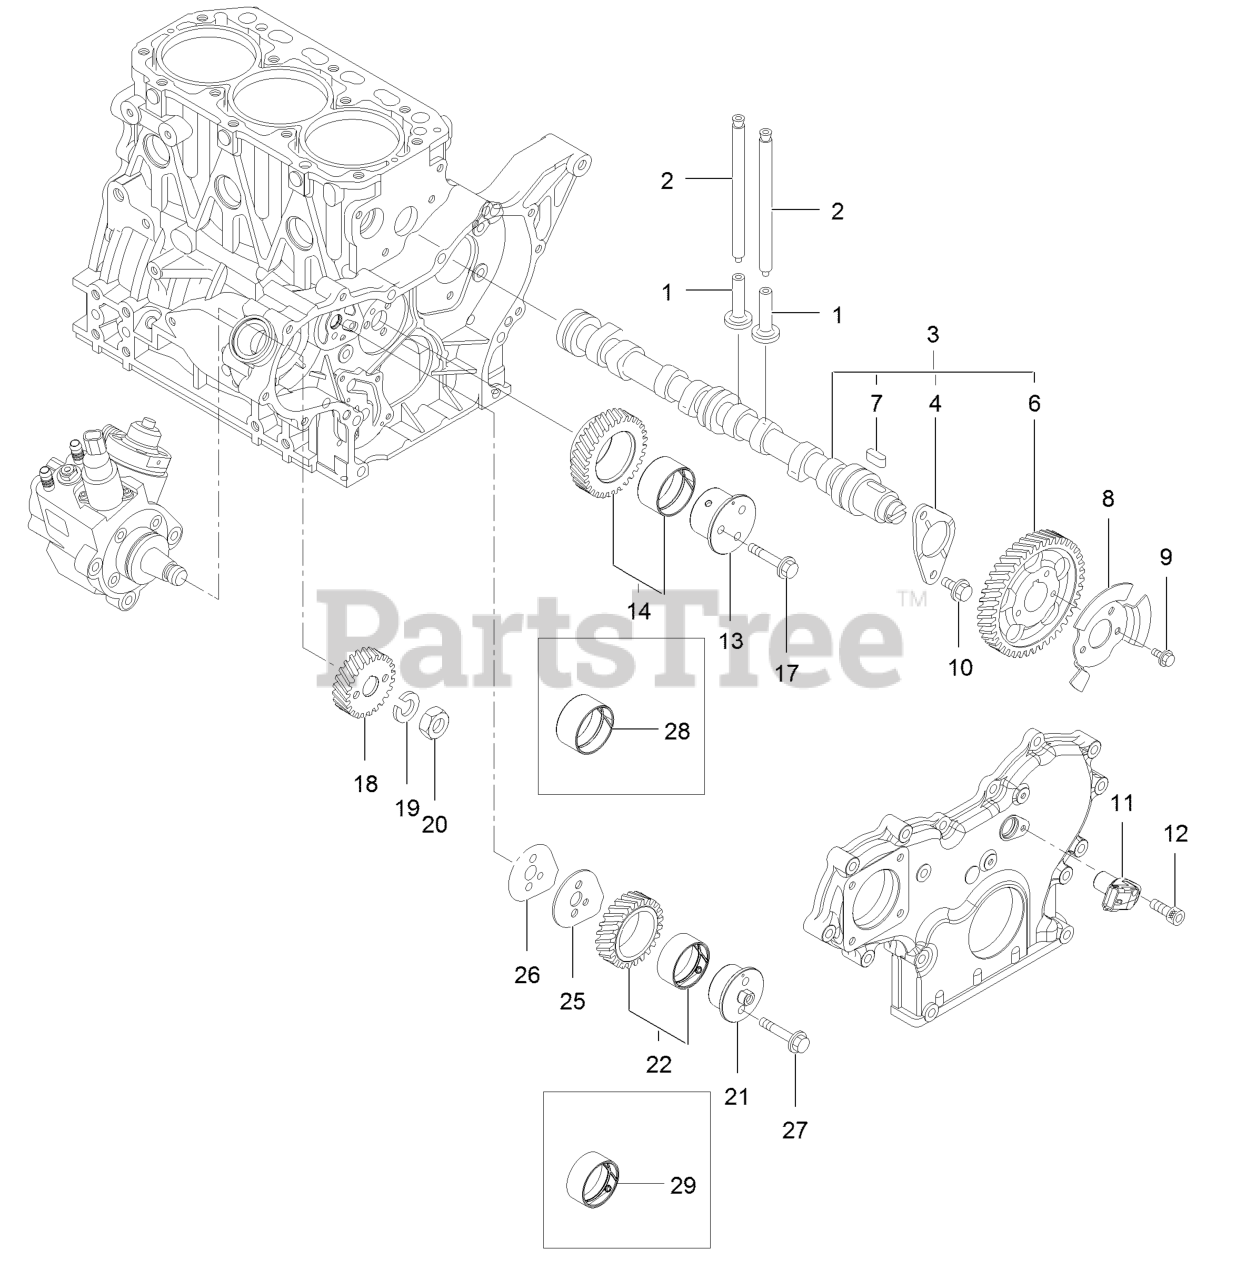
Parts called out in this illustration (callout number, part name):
2	Rod-Push
3	Camshaft ASM
4	Metal-Thrust
7	Gear-Camshaft
8	Pulser-Camshaft
11	Sensor-Rev, Gear
13	Shaft-Idle, Gear A
14	Idle Gear A ASM
18	Gear-Pump, Supply
19	Washer-Spring
20	Nut-Lock
21	Shaft-Idle, Gear B
22	Idle Gear B ASM
25	Plate-Idle, Shaft
26	Gasket-Idle, Shaft B
28	Bushing
29	Bushing
